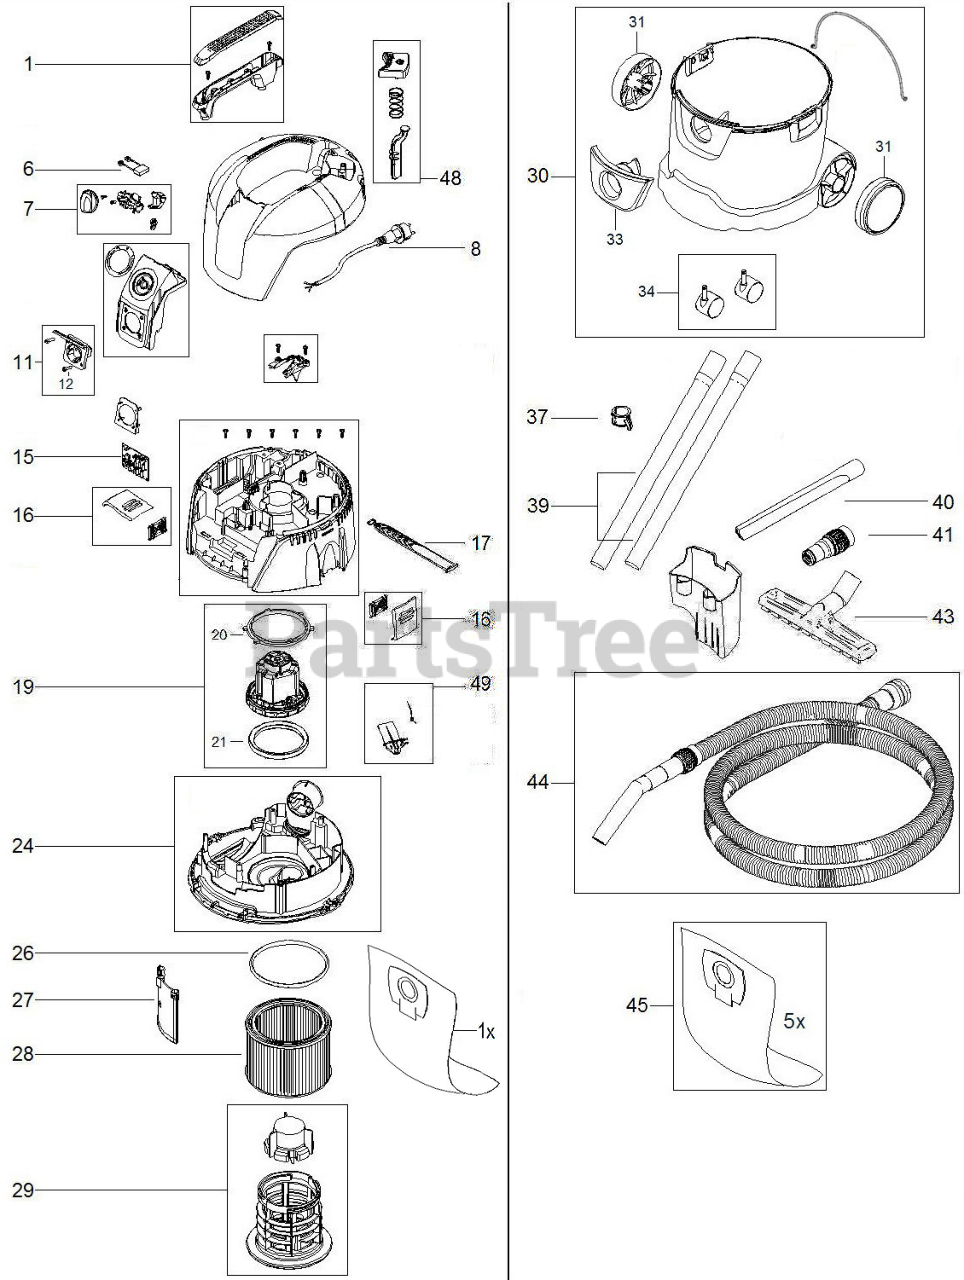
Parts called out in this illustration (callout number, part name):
6	Capacitors
19	Motor
27	Deflectors
45	WET/DRY VAC ACCY
